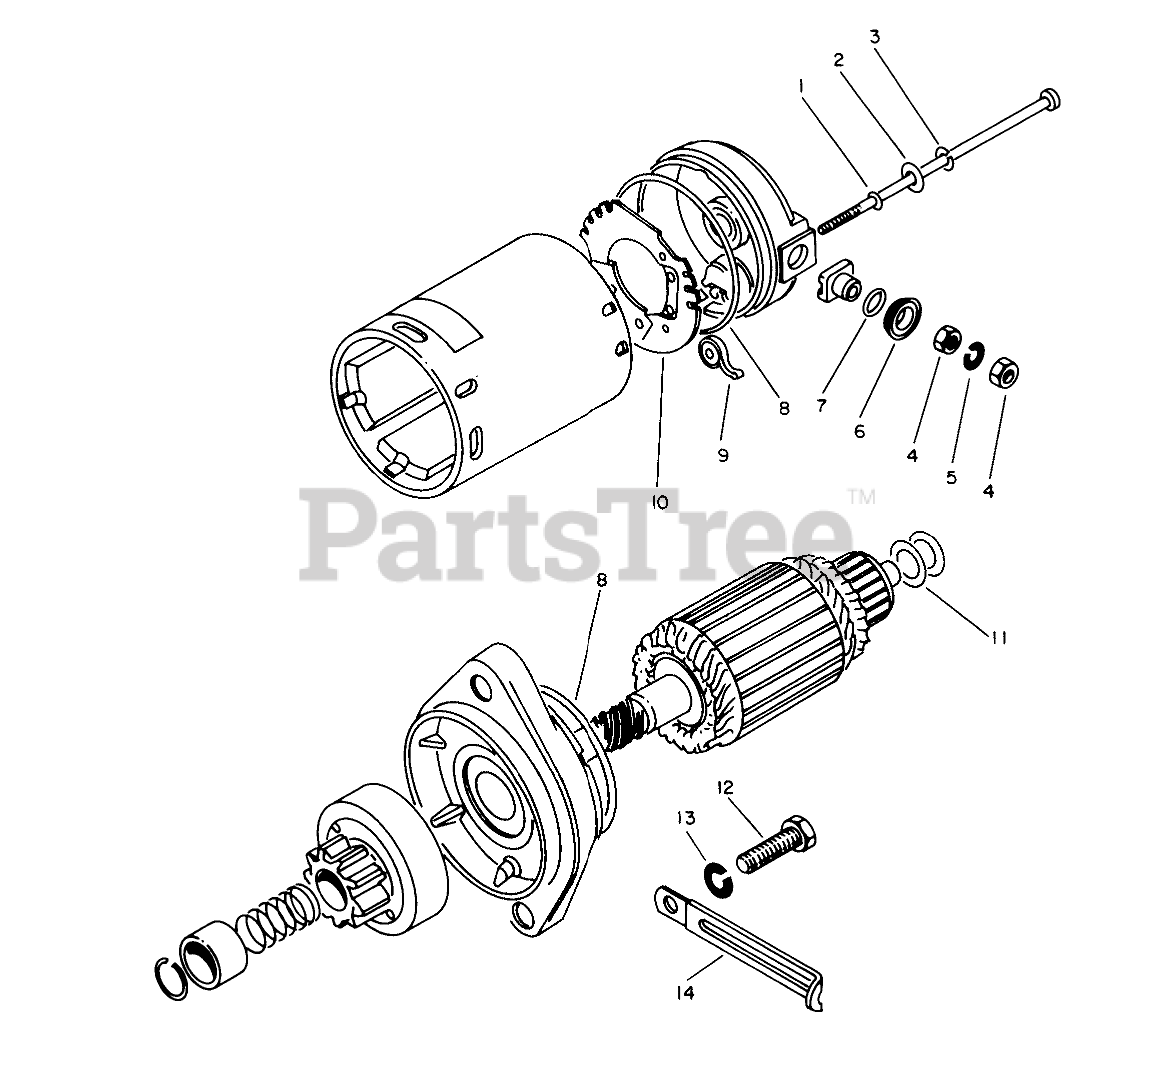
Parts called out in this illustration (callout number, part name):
1	0-Ring
2	Washer
3	Washer
5	Lockwasher
6	Bushing
7	0 Ring
8	0 Ring
9	Spring
10	Holder Assembly (Incl. Ref. #9)
13	Lockwasher
14	Clamp
